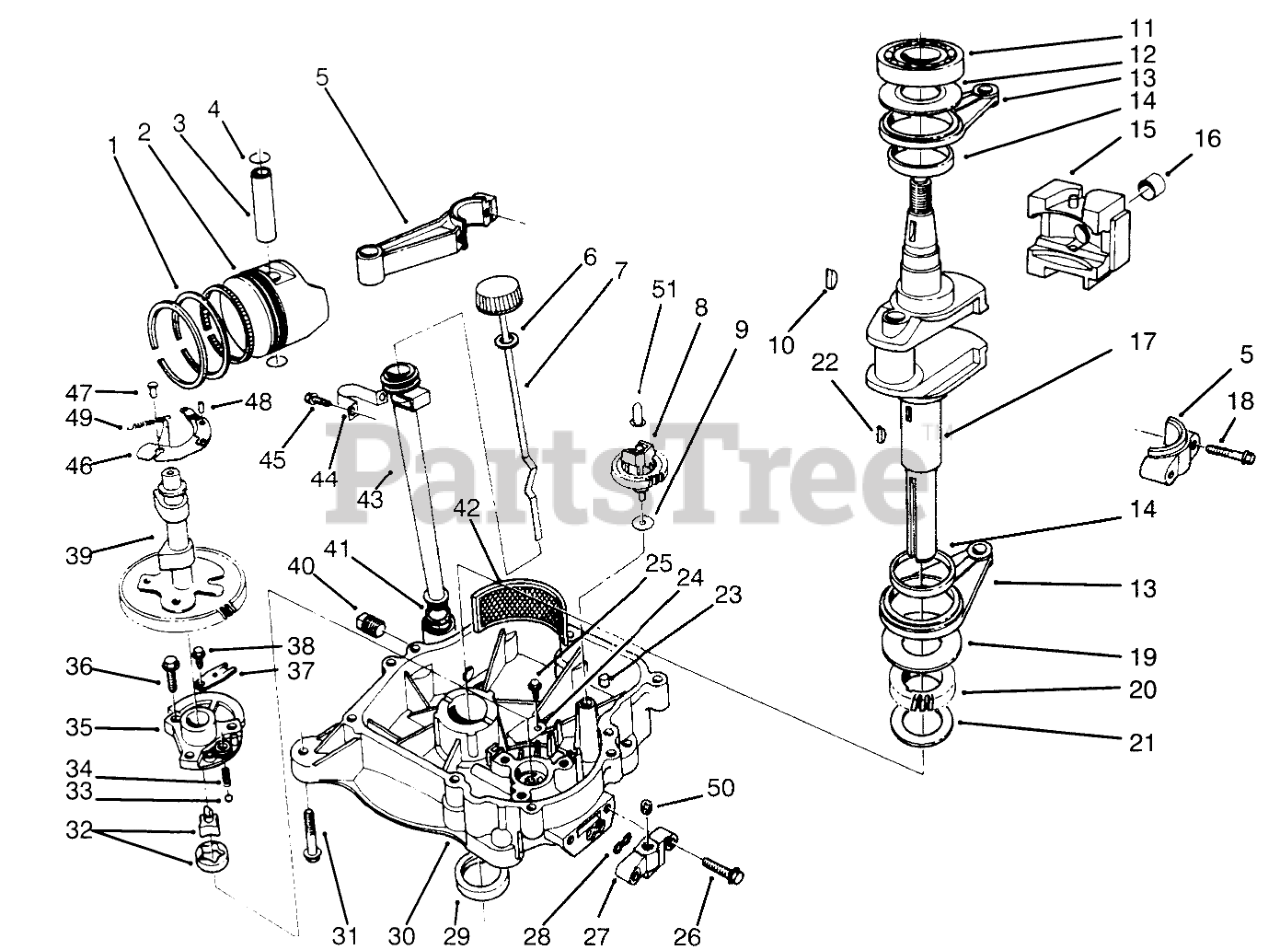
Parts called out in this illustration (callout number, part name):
1	Piston Ring Set
2	Piston
3	Pin-Piston
4	Ring-Snap
5	Rod ASM Incl #10 11
6	Gasket
7	Gauge
8	Governor ASM
9	Washer
10	Key
11	Ball Bearing
12	Spacer
13	Rod Assembly
14	Bearing Plane
15	Weight
16	Bushing
17	Crankshaft
18	Bolt
19	Spacer
20	Gear
21	Shim (1.18)
22	Key
23	Pin
24	Plate
25	Bolt
26	Bolt
27	Cover
28	Seal
29	Oil Seal
30	Gasket
31	Bolt-Flanged (8X45)
32	Pump ASM-Oil
33	Ball
34	Spring
35	Cover-Pump
36	Bolt
37	Plate
38	BOLT-FLANGED (6X10)
39	Camshaft Compression
40	Plug
41	O-RING (16mm)
42	Filter-Oil
43	Filler
44	Clamp
45	Bolt
46	Decompressor
47	Pin
48	Pin
49	Spring
50	Plug
51	Sleeve
